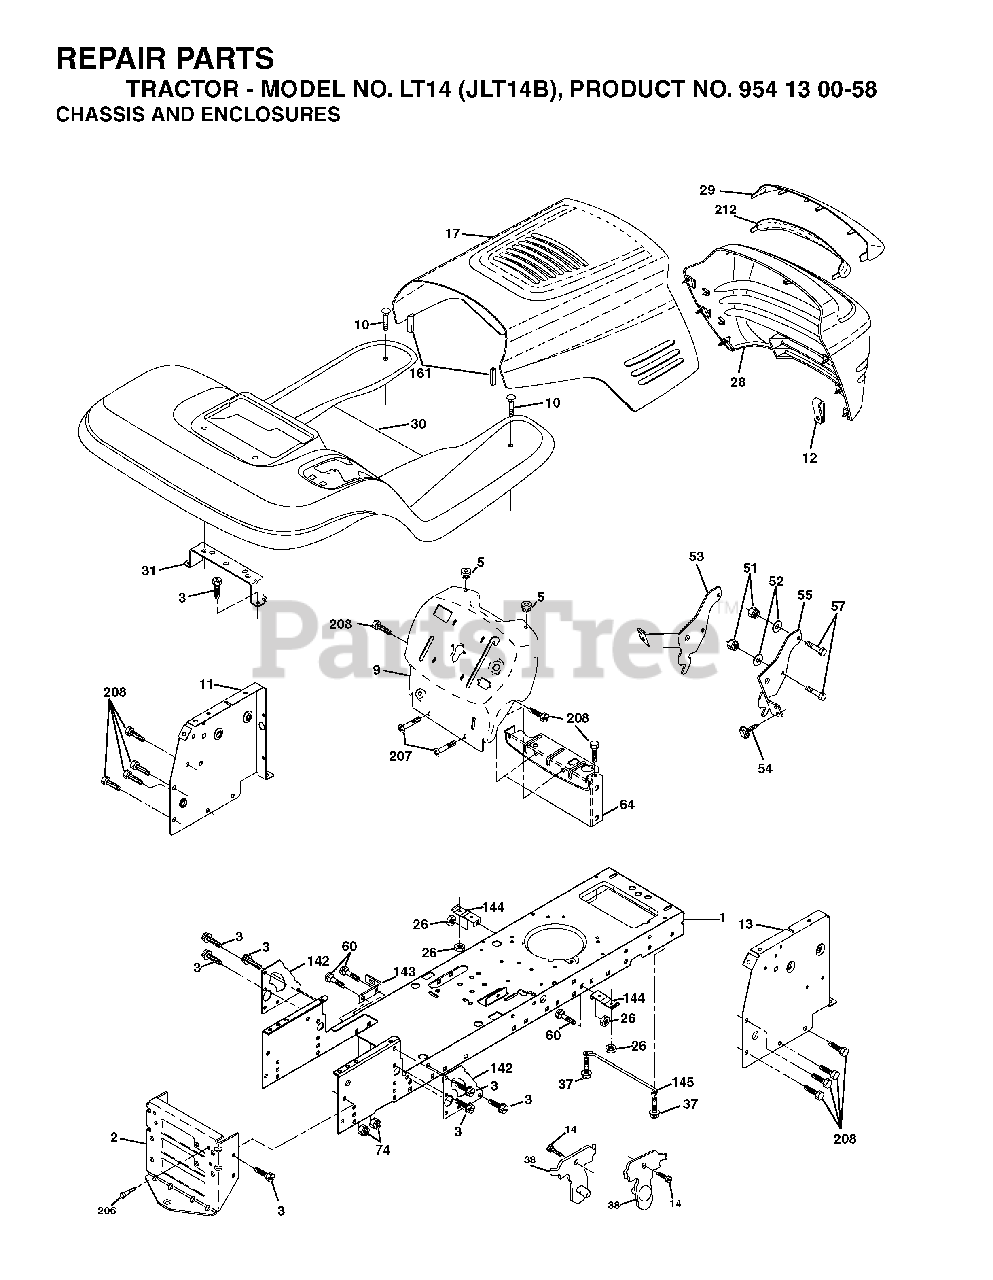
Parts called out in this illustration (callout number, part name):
1	CHASSIS STAMPING
2	DRAWBAR, 12GA
3	SCREW 3/8-16X3/4
5	BUMPER.RUBBER.HOOD
10	BOLT D
11	PANEL.DASH.LH.LTX
13	PANEL DASH RH
26	NUT
38	BRACKET.ASM.PIVOT.MOWER.REAR
51	LOCKNUT
57	BOLT
64	DASH LOWER
74	LOCKNUT
142	PLATE REINFORCEMENT
143	BRACKET, SWAY BAR
144	BRKT, FOOT REST
145	ROD PIVOT CHASSIS/HOOD
161	EXTRUSION BUMPER
206	SHOULDER BOLT 5/16-18TT
207	SCREW, 5/16-18 X 1/2
208	SCREW 3/8-16X1/2
